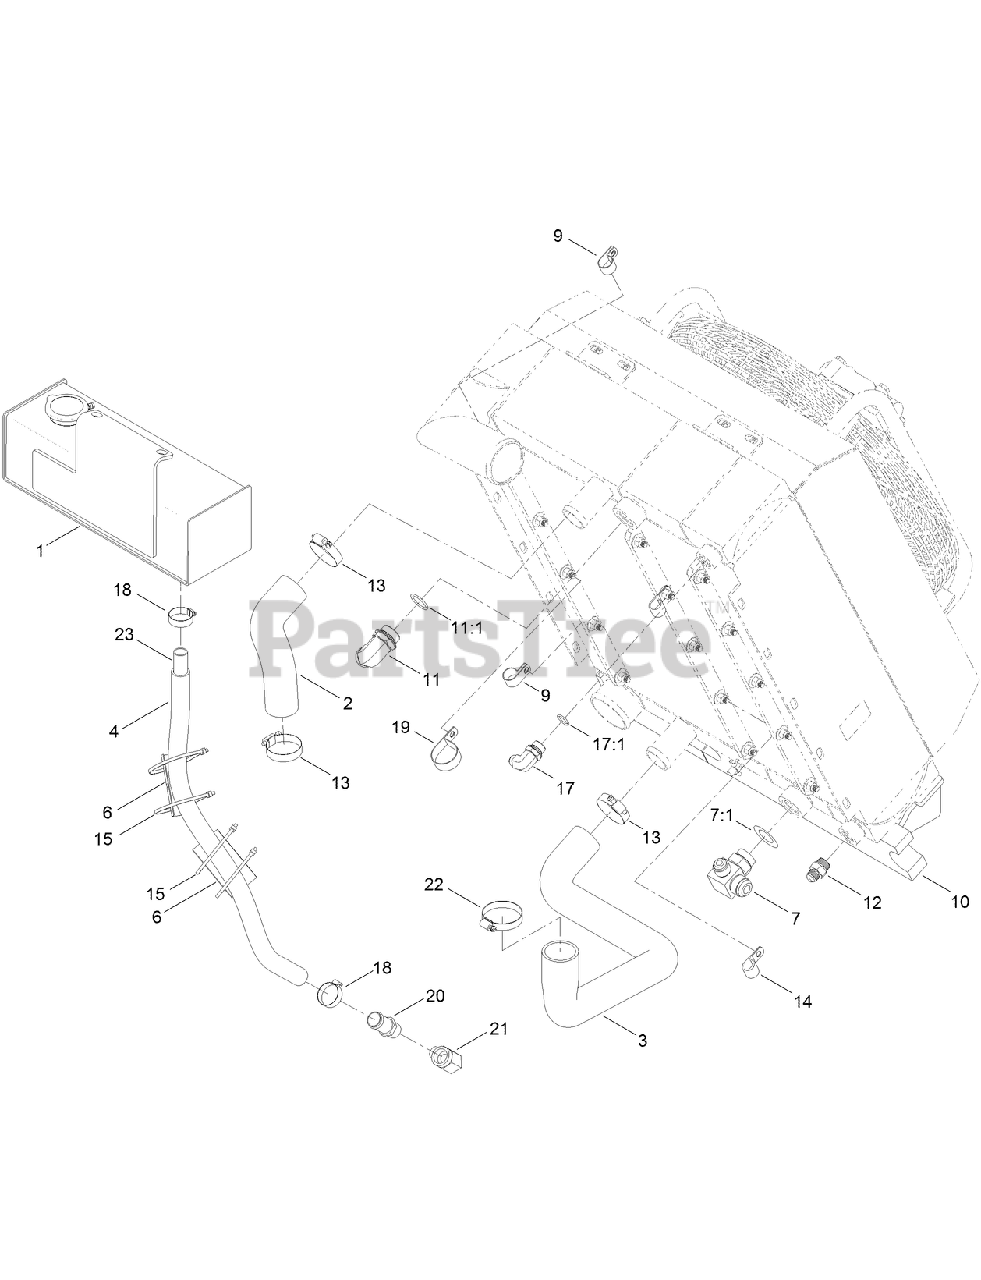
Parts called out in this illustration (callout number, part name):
1	TANK-RECOVERY, COOLANT
2	HOSE-RADIATOR, TOP
3	HOSE-RADIATOR, BOTTOM
4	HOSE-INLET
6	PROTECTOR-HOSE
7	FITTING-HYD, SPECIAL
7:1	O-RING
9	CLAMP-R
10	SEAL-FOAM
11	ELBOW-90 DEG
11:1	O-RING
12	FITTING-STRAIGHT
13	CLAMP-HOSE
14	CLAMP-R
15	TIE-CABLE
17	FITTING-90 DEG
17:1	O-RING
18	CLAMP-HOSE
19	CLAMP-R
20	FITTING-STR
21	FITTING-ELBOW, 90 DEG
22	CLAMP-HOSE
23	SLEEVE-INLET
